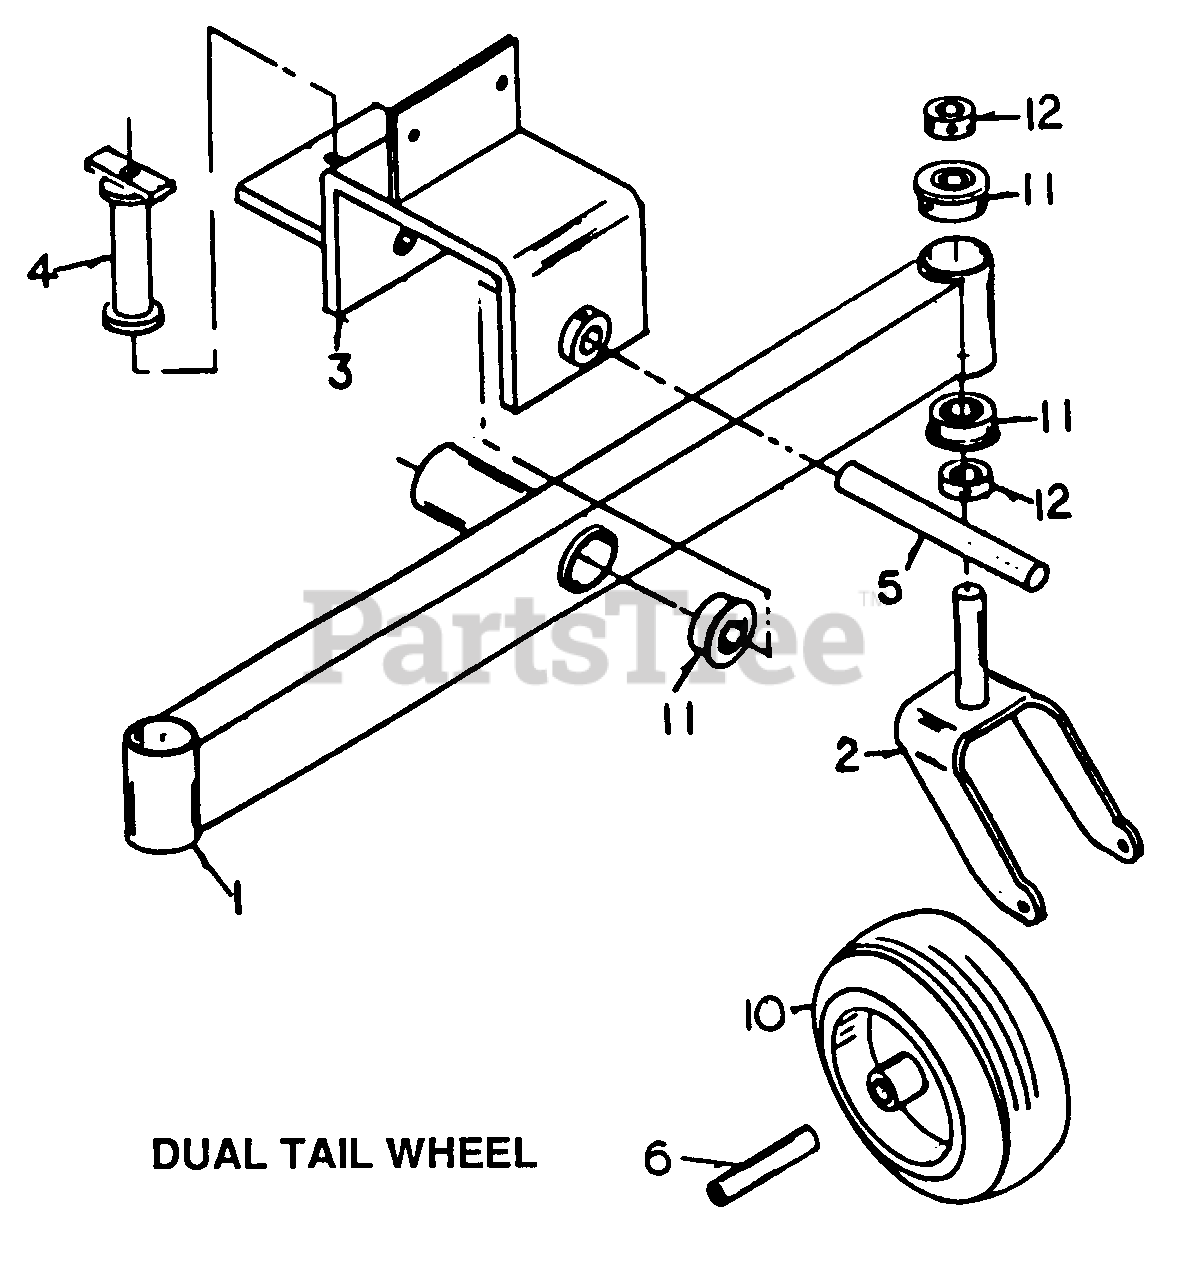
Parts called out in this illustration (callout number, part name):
1	Dual Tail Wheel Axle
2	Dual Tail Wheel Fork
3	Dual Tail Wheel Mount
4	Dual Tail Wheel Tube Block
6	Tail Wheel Axle
10	Tail Wheel Assembly
12	Set Collar, 1"
